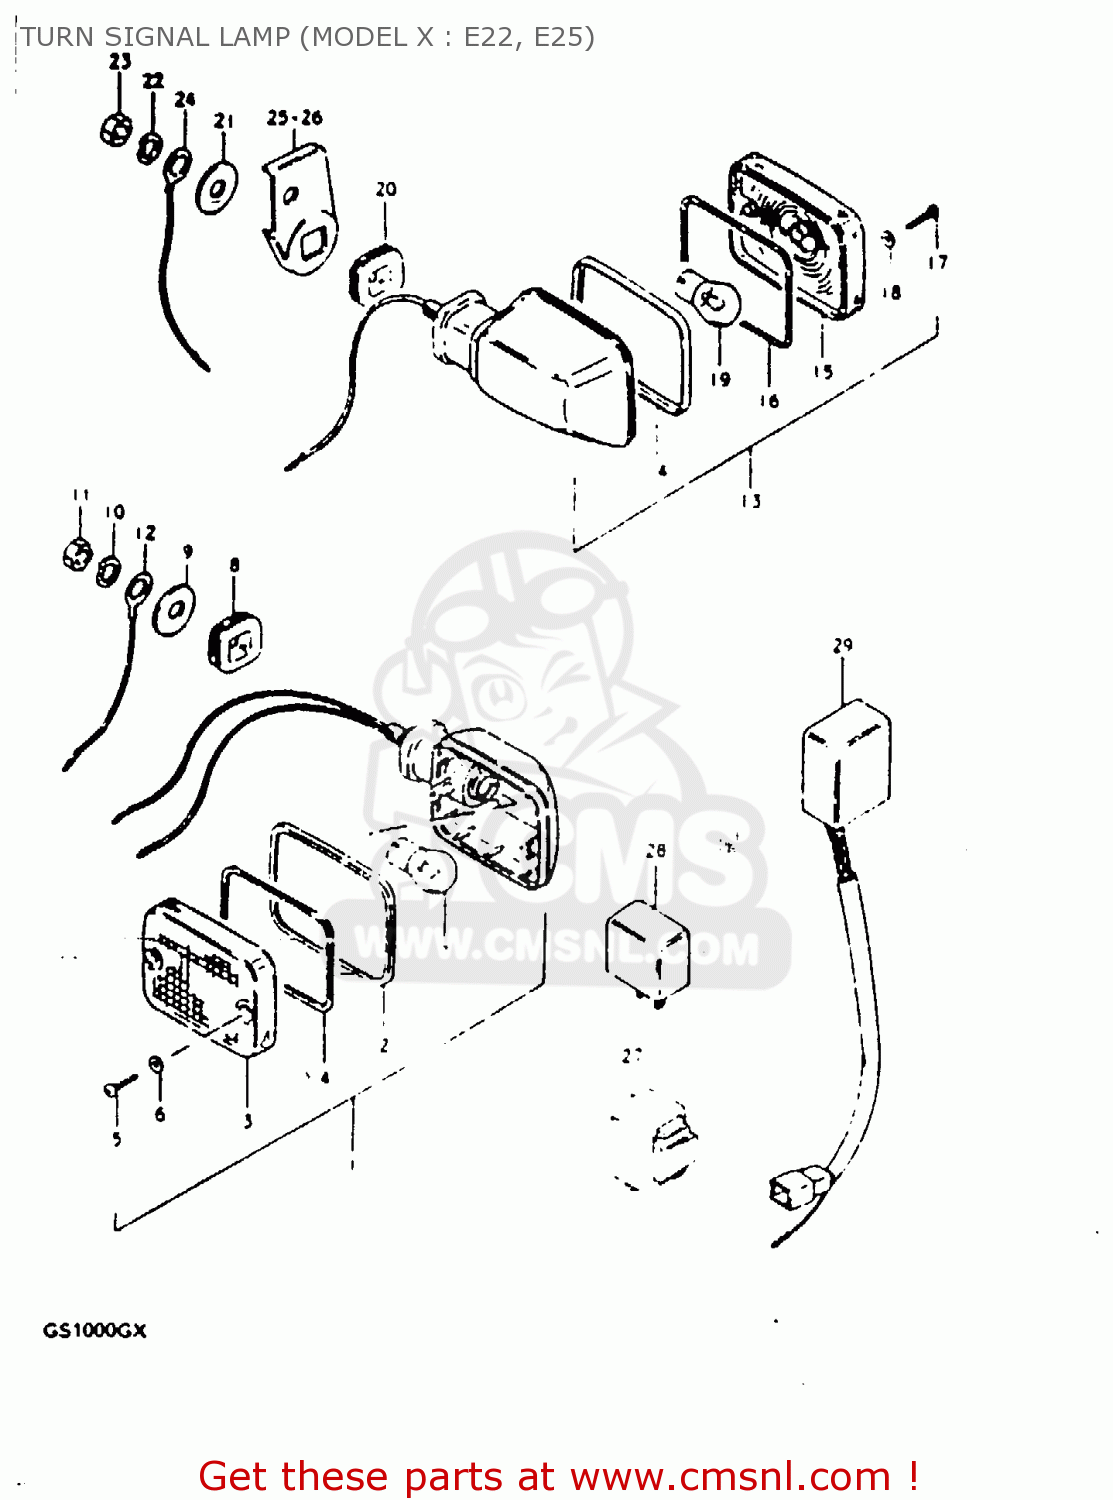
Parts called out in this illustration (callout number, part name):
1	LAMP, REAR TURN SIGNAL
2	RIM
3	LENS
4	GASKET (NAS)
5	SCREW
6	GASKET (NAS)
7	BULB(12V21W)
8	CUSHION
9	WASHER (10.5X30X2.3)
10	LOCK WASHER
11	NUT
12	LEAD WIRE,EARTH
13	LAMP, REAR TURN SIGNAL
14	RIM
15	LENS
16	GASKET (NAS)
17	SCREW
18	GASKET (NAS)
19	BULB(12V21W)
20	CUSHION
21	WASHER (10.5X30X2.3)
22	LOCK WASHER
23	NUT
24	LEAD WIRE,EARTH
25	BRACKET,RR TURNSIGNAL LAMP,R
26	BRACKET,RR TURNSIGNAL LAMP,L
27	RELAY, TURN SIGNAL
28	RELAY ASSY,TURNSIGNAL
29	UNIT,TURN SIGNAL CONTROL
